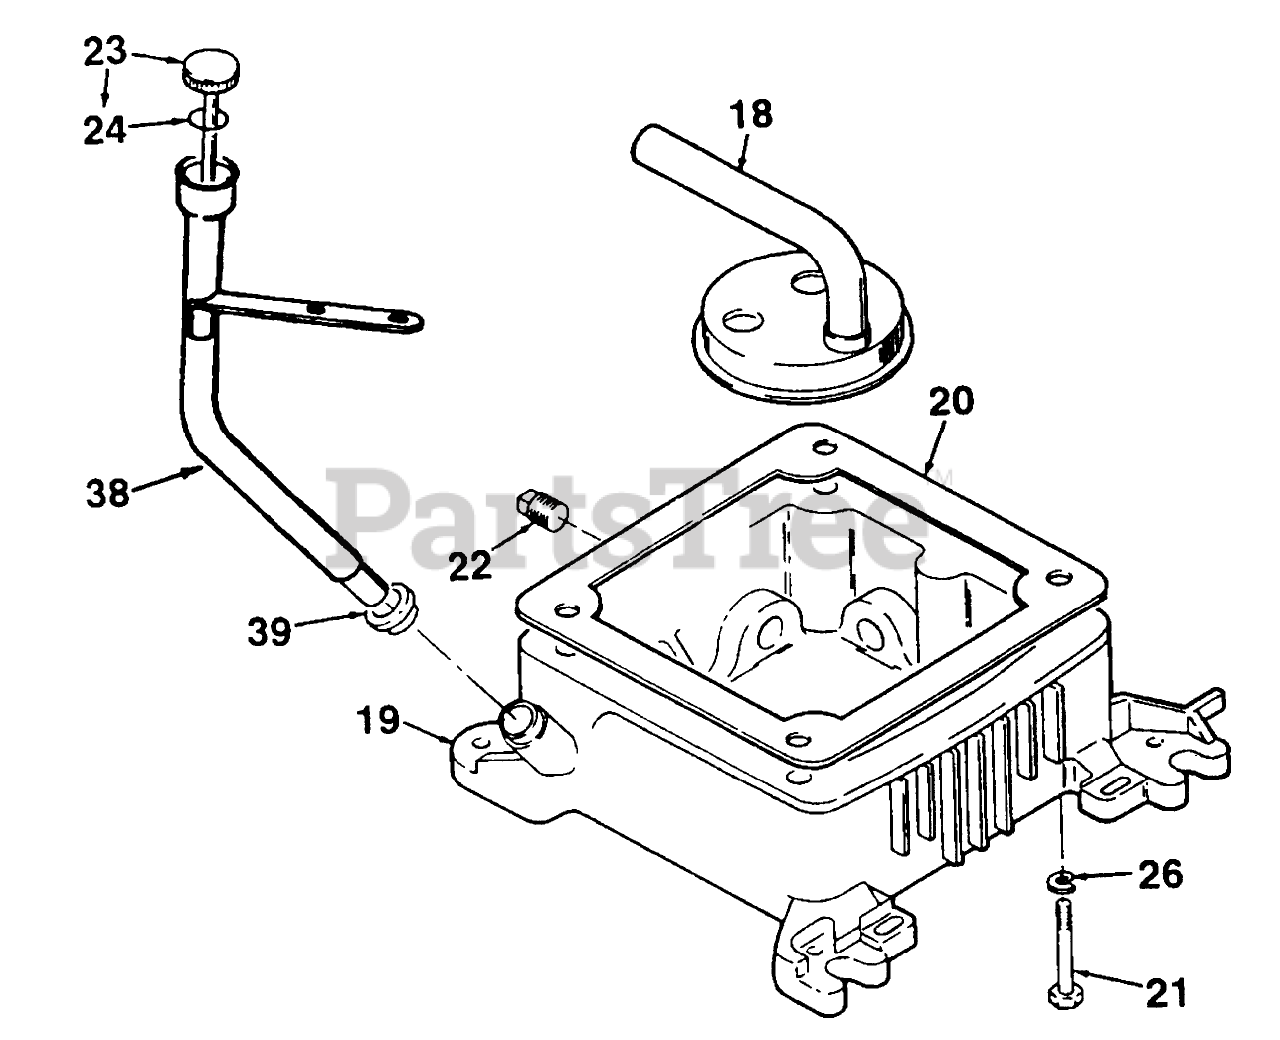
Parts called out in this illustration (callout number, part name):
18	CUP-OIL PUMP INTAKE
19	Base-Oil (Incl. Plugs)
20	GASKET
21	SCREW-HH
23	Oil Fill Cap & Indicator (Incl. O-Ring)
24	SEAL 0-RING
26	WASHER-FLAT
38	TUBE-OIL FILTER
39	SEAL-OIL FILL TUBE
